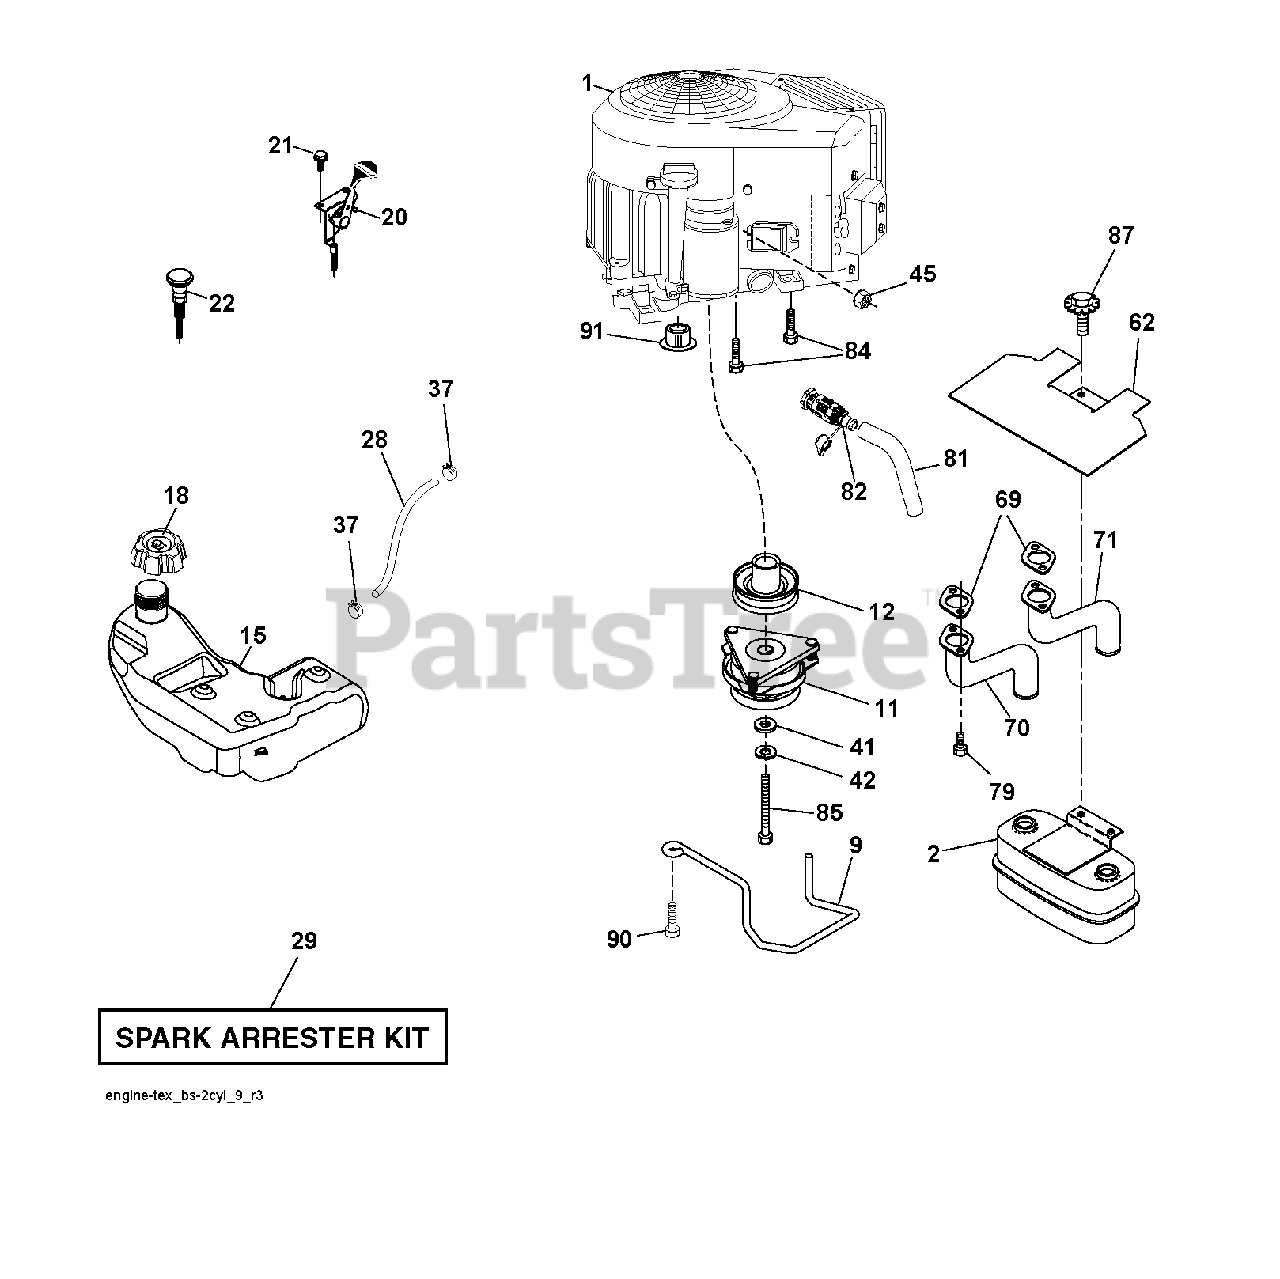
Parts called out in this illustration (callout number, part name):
2	MUFFLER.TWIN.CYL.LOW.TONE
9	KEEPER.BELT.ENGINE.4.2
11	CLUTCH ELECTRIC
12	PULLEY ENGINE
15	TANK.FUEL.4GAL
18	CAP.ASM.FUEL.TANK.3"BLACK
20	THROTTLE CABLE
21	SCREW.#10 X 0.750.BOS THREAD
22	CONTROL CHOKE
28	LINE.FUEL.20
29	ARRESTER SPARK (OPTIONAL)
37	HOSE CLAMP
42	LOCKWASHER
45	NUT
62	SHIELD.HEAT.MUFFLER
69	GASKET.MUFFLER
70	TUBE MANIFOLD LH
71	EXHAUST TUBE RH
79	SCREW.SOCKET.HEAD.5/16-18
81	TUBE, DRAIN OIL ASM.
82	VALUE.OIL.DRAIN
84	SCREW.3/8-16
85	BOLT HEX 7/16-20 X 3.75 GR. 5
87	BOLT, 5/16-18 X 1 3/4
90	SCREW 3/8-16X1
91	BUSHING.1.375OD
